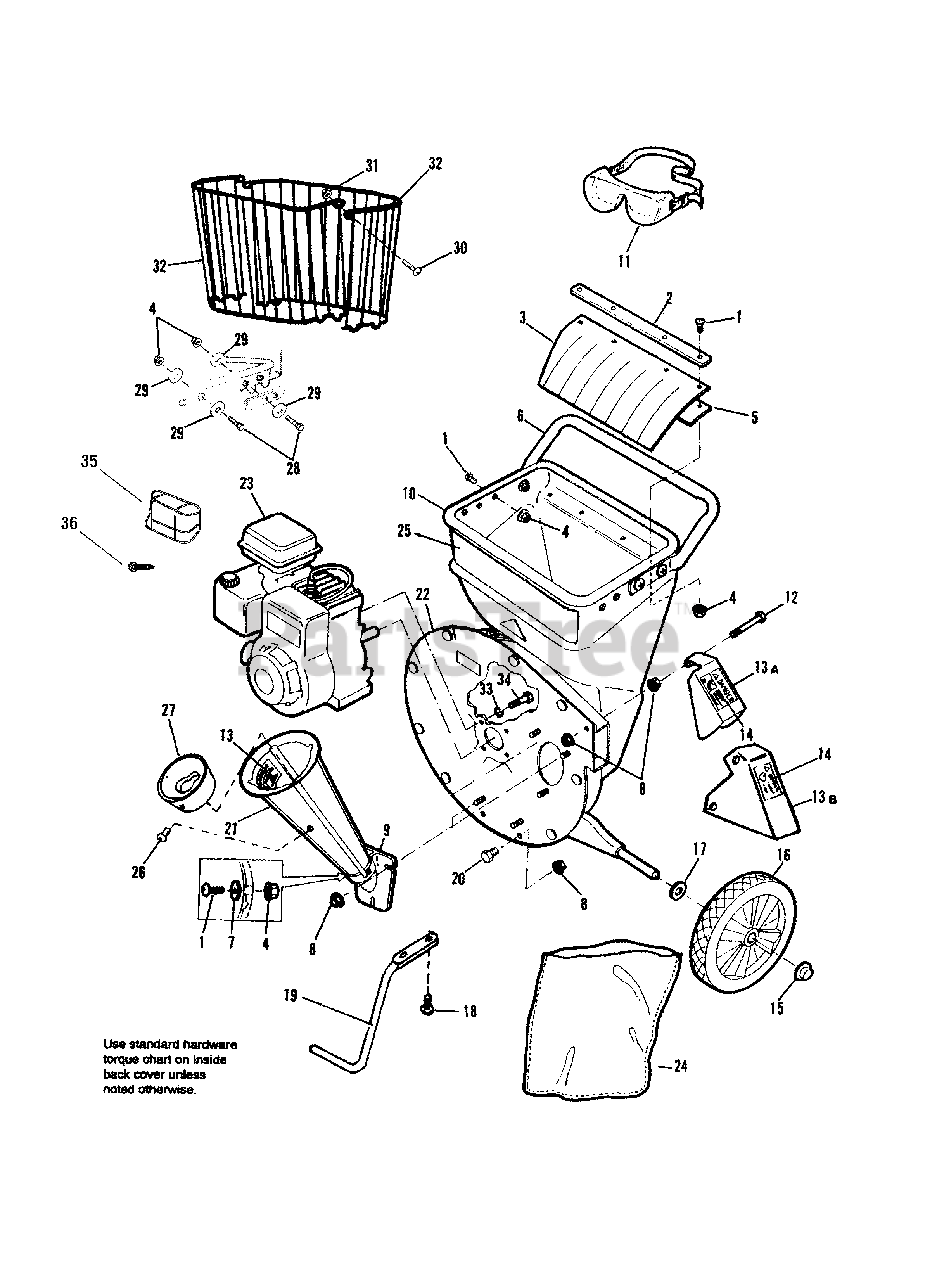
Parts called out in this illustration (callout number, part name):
1	SCREW, Hex, Button Hd., 1/4-20 x 3/4 (Qty.10 used on European model)
2	RETAINING STRIP, Hopper Guard
3	GUARD, Hopper
4	NUT, Flange, 2-Way Lock, 1/4-20 (Qty.10 used on European model)
5	SUPPORT, Hopper Guard
7	WASHER, Plain, 17/64 x 518 x 3164
8	NUT, Whiz, 5/16-18
9	CASTING, Chipper Cone, 3"
10	HOPPER, Orange
10	HOPPER, Yellow
10	HOPPER, Orange (European model only)
11	SAFETY GOGGLES
12	CAPSCREW, Hex, 5/16-18 x 3-1/4, Gr.5
13B	DEFLECTOR, Fi x ed (European model only)
14	DECAL, Danger
15	PUSH NUT, 1/2
16	WHEEL & TIRE ASSY., 1-3/4 x 12 (5/14 Only)
16	WHEEL & TIRE ASSY., 2-1/4 x 12 (8/14 Only)
17	WASHER, Plain, 17/32Plain, 17/32 x 1-1/4 x 5/64
18	SCREW, Taptite, 3/8 16 x 1-1/4
20	CAPSCREW, Hex, 5/16-18 x 5/8
21	CONE, Chipper, Orange
21	CONE, Chipper, Yellow
21	CONE, Chipper, Orange (European model only)
22	ENGINE PLATE ASSY.
23	ENGINE, 5 HP, Briggs & Stratton ENGINE, 8 HP, Briggs & Stratton
24	COLLECTION BAG, 24" x 36"
25	DECAL, 5514 Chipper Shredder
25	DECAL, 5/14, Baker
25	DECAL, 8/14, Simplicity
25	DECAL, 8/14, Baker
26	SCREW, Round. Hd., Phillips, 1/4-20 x 1/2 (European model only)
27	INSERT, Cone (European model only)
28	CAPSCREW, Hex, 1/4-20 x 1, Gr. 5 (European model only)
28	ENGINE, 5.5 HP Briggs & Stratton
29	WASHER, Plain, 1/4 x 1-1/4 x 5/64 (European model only)
30	SCREW, Truss Hd., 5/16-18 x 3/4 (European model only)
31	NUT, Flange, Whiz Lock, 5/16-18 (European model only)
32	HOPPER HALF, Upper (European model only)
33	Lockwasher, 5/16
34	CAPSCREW, Hex Hd., 5/16-24 x 3/4
35	GUARD, Muffler 5.5 HP
36	SCREW, Self Tap Hex Washer Head #8 x 3/4
